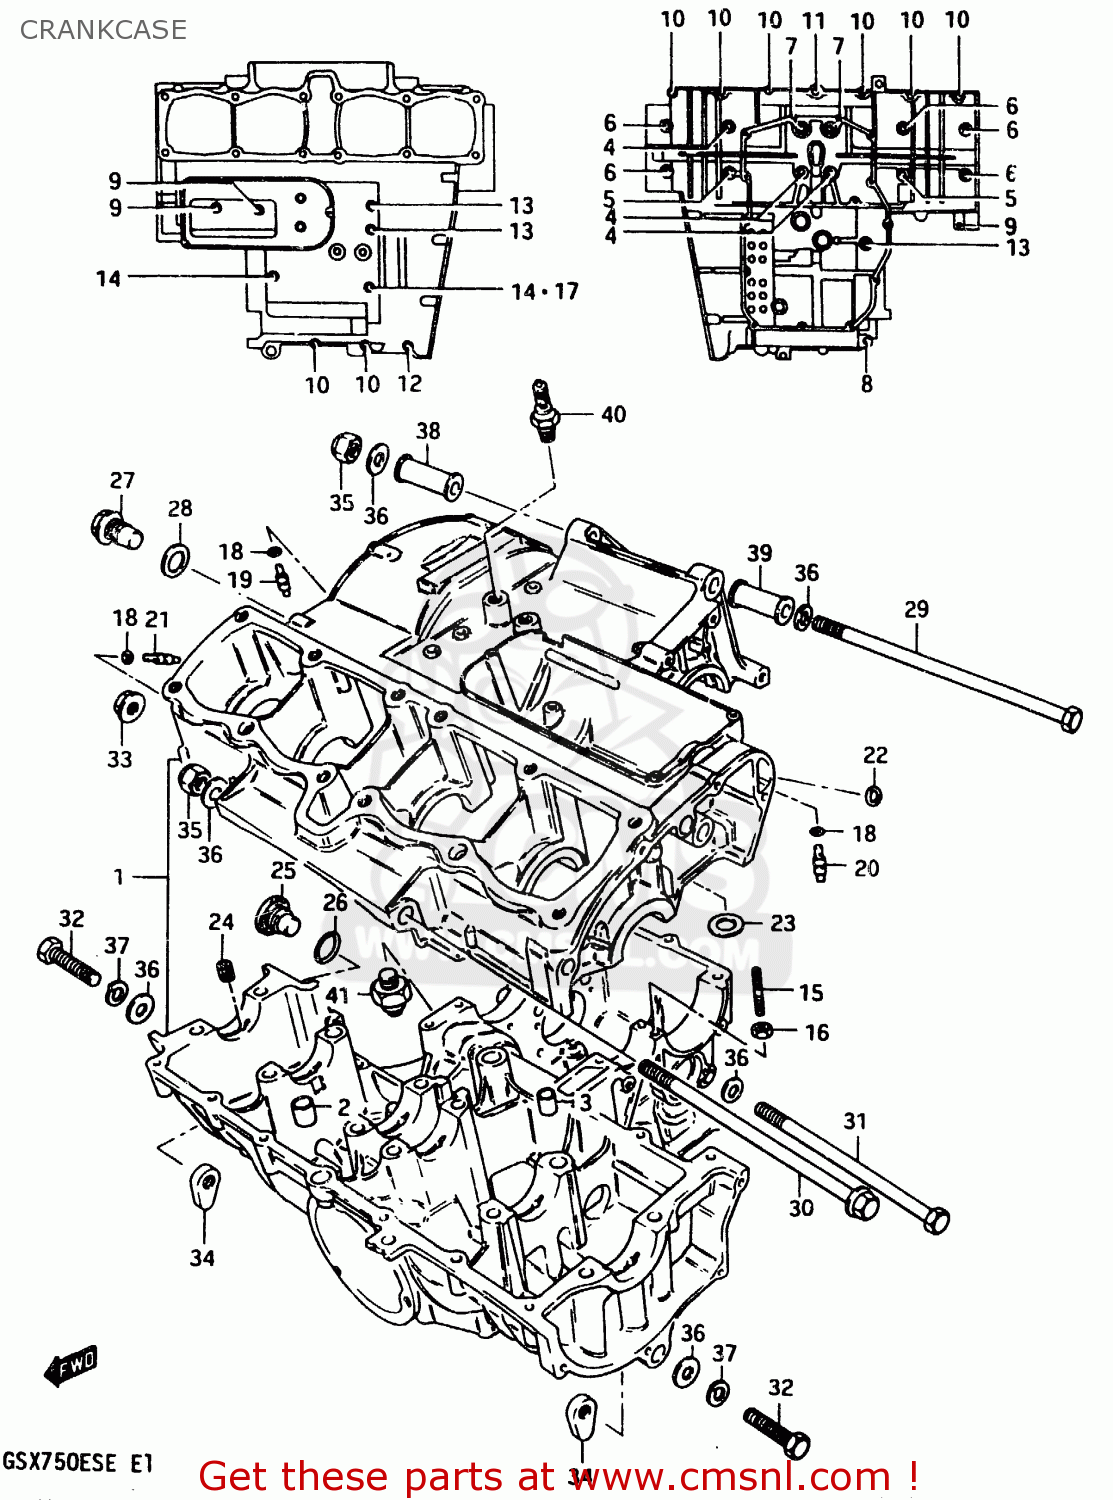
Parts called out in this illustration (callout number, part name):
1	CRANKCASE SET
2	PIN(10.4X13X22)
3	PIN (11X20)(SUS)
4	BOLT(8X120)
5	BOLT(8X135)
6	BOLT
7	BOLT
8	BOLT 8X60
9	BOLT
10	BOLT (6X40)
11	BOLT 6X50
12	BOLT 6X55
13	BOLT
14	BOLT (5X95)
15	STUD BOLT (6X45)
16	NUT
17	GASKET(6.2X13X1.2) (NAS)
18	O RING(D:1.2,ID:4)
19	JET,OIL GALLERY
20	JET(8)
21	JET,OIL
22	O RING(D:3.2,ID:12.9)
23	WASHER,THRUST
24	JET,AIR
25	PLUG
26	O RING(D:2.4,ID:16.8)
27	PLUG
28	GASKET(14X19.2X2) (NAS)
29	BOLT 10X255
30	BOLT
31	BOLT
32	BOLT
33	NUT 10MM
34	NUT
35	NUT
36	WASHER
37	LOCK WASHER
38	SPACER,ENGINE MOUNT
39	SPACER,ENGINE MOUNT(L:50)
40	GAUGE ASSEMBLY,OIL TEMPERATURE
41	SWITCH ASSEMBLY
